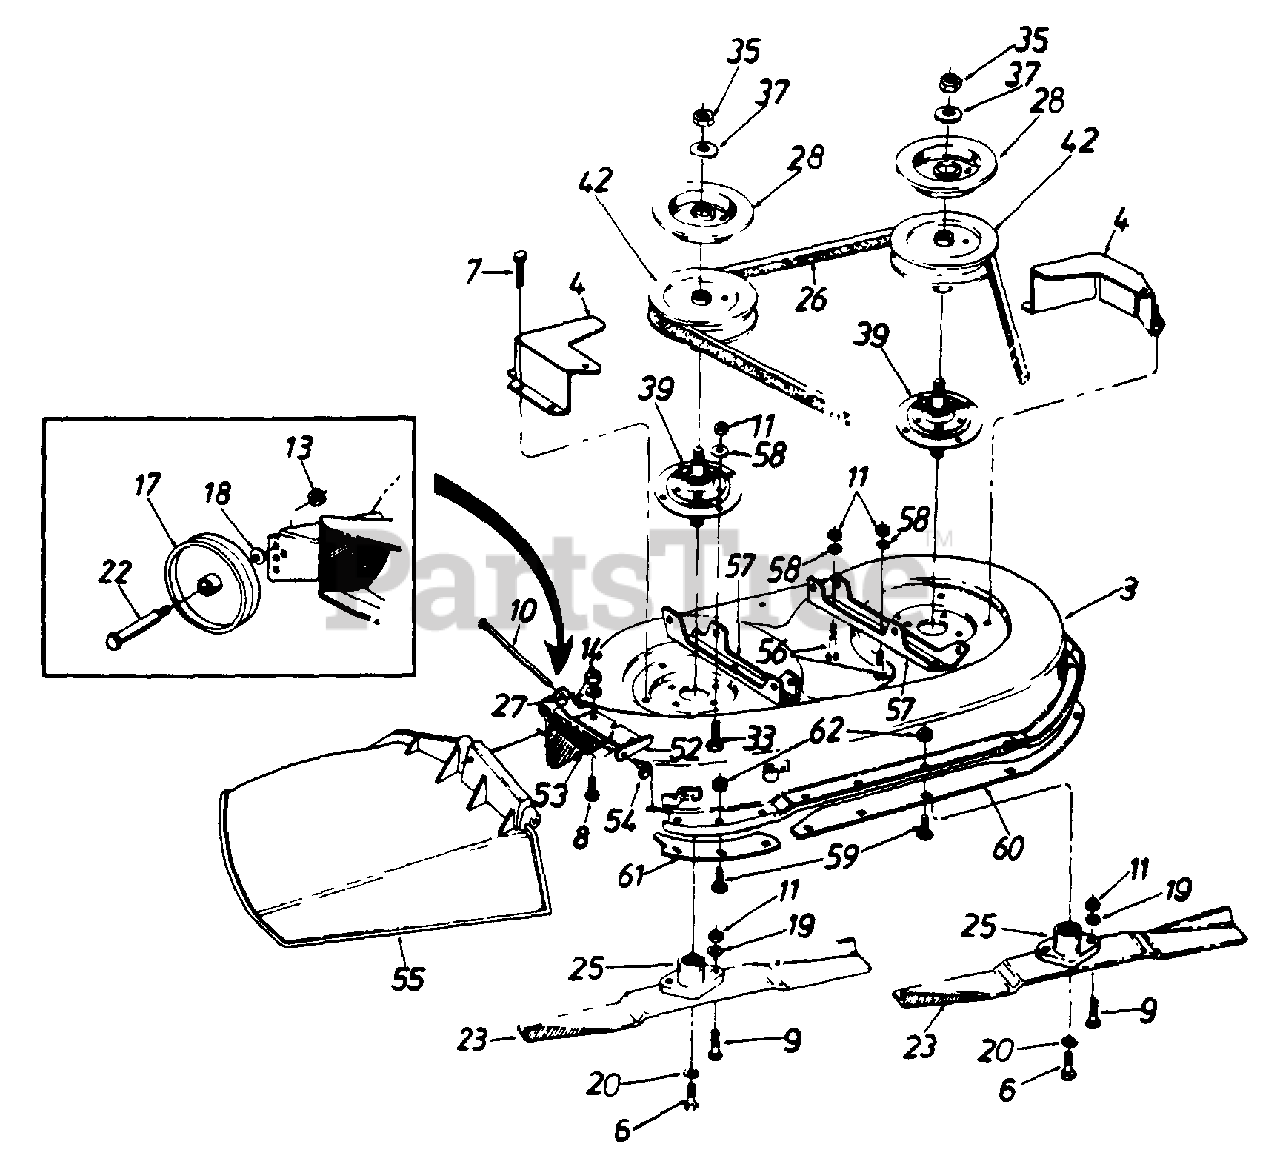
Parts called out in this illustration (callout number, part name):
6	Hex Bolt 3/8-24 x 1.0" Lg.
7	Hex Wash. Hd. TT-Tap Scr. 1/4-20 x .5" Lg.
8	Hex Bolt 1/4-20 x .62"
9	Hex Bolt Special 5/16-24 x 1.0"
10	Hinge Pin
11	Hex Nut 5/16-24 Thd.
13	Hex Top Nut 3/8-16 Thd.
14	Hex Nut 1/4-20 Thd.
17	Deck Wheel - 5"
18	Bell-Wash. .40" I.D. x .88" O.D.
19	L-Wash. 5/16" I.D.
20	L-Wash. 3/8" I.D. - H.D.
22	Shld. Bolt .498" Dia. x 1.53"
23	High-Lift Blade
25	Blade Adapter
26	V-Belt
27	Bell-Wash. 1/4" I.D.
28	Brake Disc
33	Hex Bolt 5/16-24 x .75" Lg
35	Hex Jam Nut 5/8-18 Thd.
37	L-Wash. 5/8" I.D.
39	Blade Spindle Ass'y. Comp.
42	5.5" Dia. Pulley
52	Hinge Mtg. Brkt.
53	Torsion Spring
54	Push Nut
55	Chute Ass'y. Comp.
56	Hex Bolt 5/16-24 x .75" Lg.
59	Carr. Bolt 1/4-20 x .5" Lg.
62	Hex Sems Nut 1/4-20 Thd.
